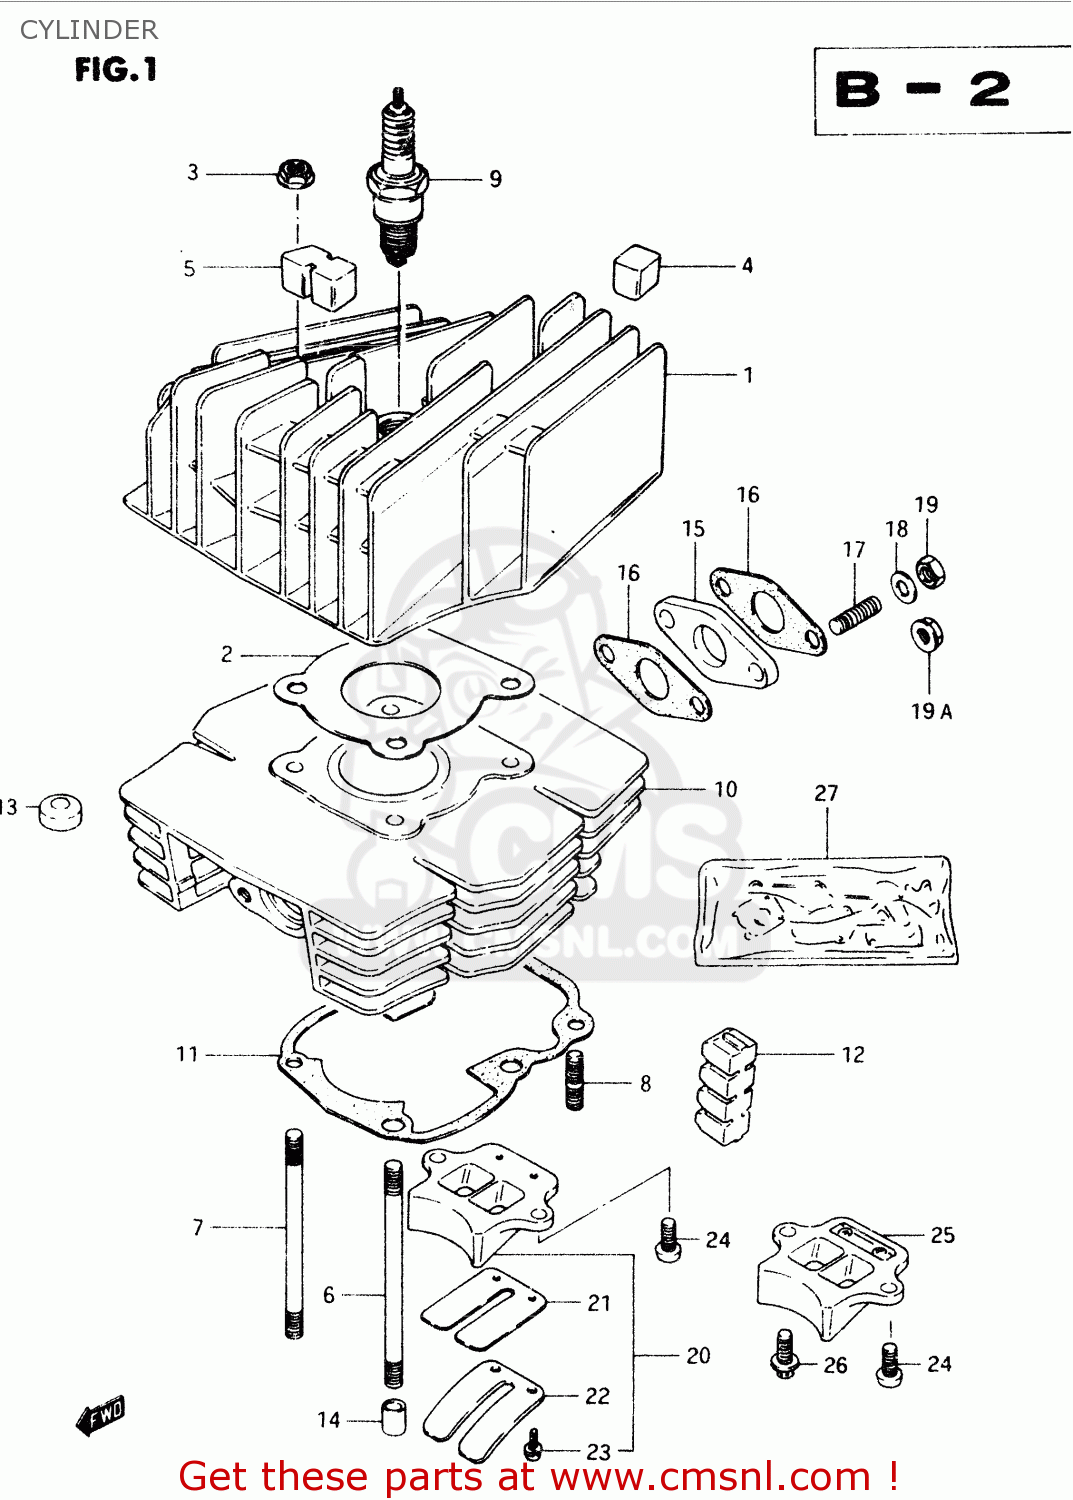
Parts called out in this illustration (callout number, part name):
1	HEAD,CYLINDER
2	GASKET,CYLINDER HEAD (NAS)
3	NUT
4	PAD,CYLINDER HEAD
5	PAD, RUBBER
6	STUD
7	STUD
8	STUD 6X16
9	PLUG,SPARK(BPR6ES)
10	CYLINDER
11	GASKET,CYLINDER (MCA)
12	PAD,CYLINDER
13	PAD,CYLINDER RUBBER(N1)
14	PIN
15	INSULATOR,CARBURETOR
16	GASKET,CARBURETOR (NAS)
17	STUD BOLT
18	WASHER
19	NUT 6MM
19A	NUT
20	VALVE ASSY,REED
21	VALVE,REED
22	STOPPER,REED VALVE
23	SCREW,REED VALVE
24	SCREW
25	VALVE ASSY,REED
26	SCREW(6X16)
27	GASKET SET (NAS)
